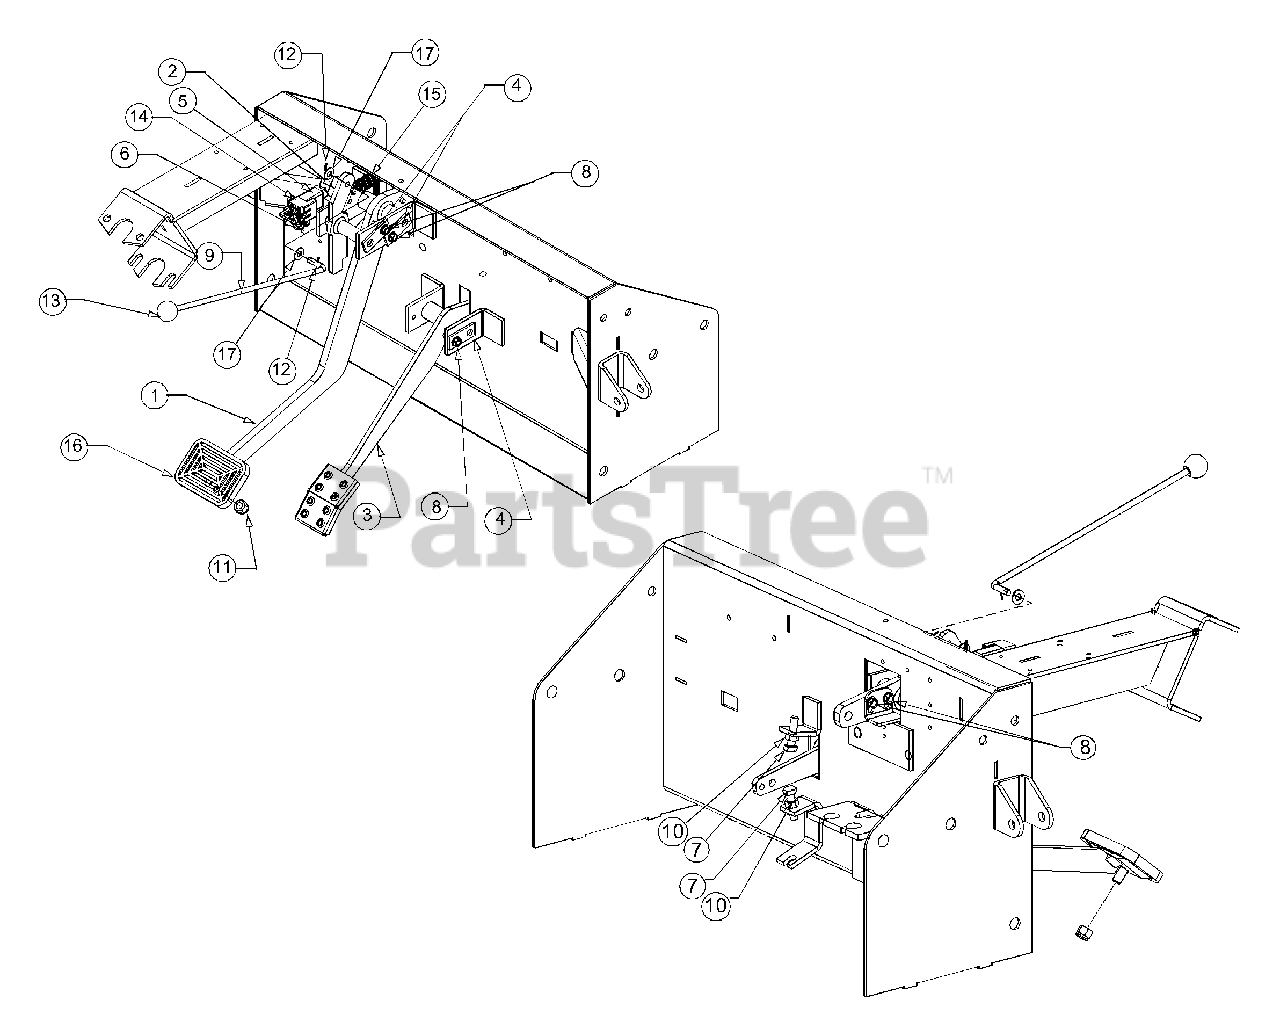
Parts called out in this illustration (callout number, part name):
3	Pedal Assembly, Throttle
4	Shaft Assembly, Pedal Pivot
5	Cover, Protective
6	Screw, Hi-Lo, 1/4-20 x .5
7	Screw, Hex 5/16-18 x 1.25
8	Screw, Self-tapping, 1/4-20, .75
9	Rod, Brake Lock
10	Nut, Hex 5/16-18
11	Nut, Hexlock, 3/8 - 24
12	Pin, Cotter 1/16 x .75
13	Knob, Ball
14	Snap Mount Switch, Interlock
15	Spring, Extension, .637 x 2.972
16	Pad, Brake Pedal
17	Washer, Flat .25 x .630 x .0515
